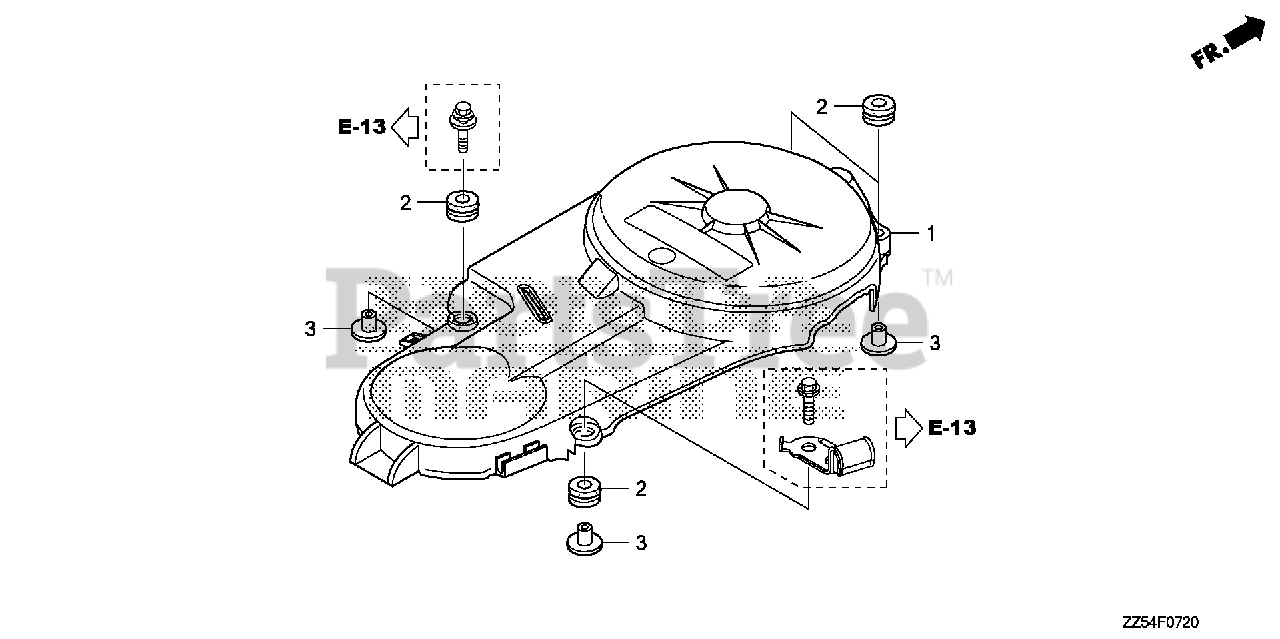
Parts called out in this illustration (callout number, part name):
1	COVER, ALTERNATOR
2	GROMMET, CASE (LOWER)
3	COLLAR, MODULE IGNITION CONTROL CASE (CDI)
